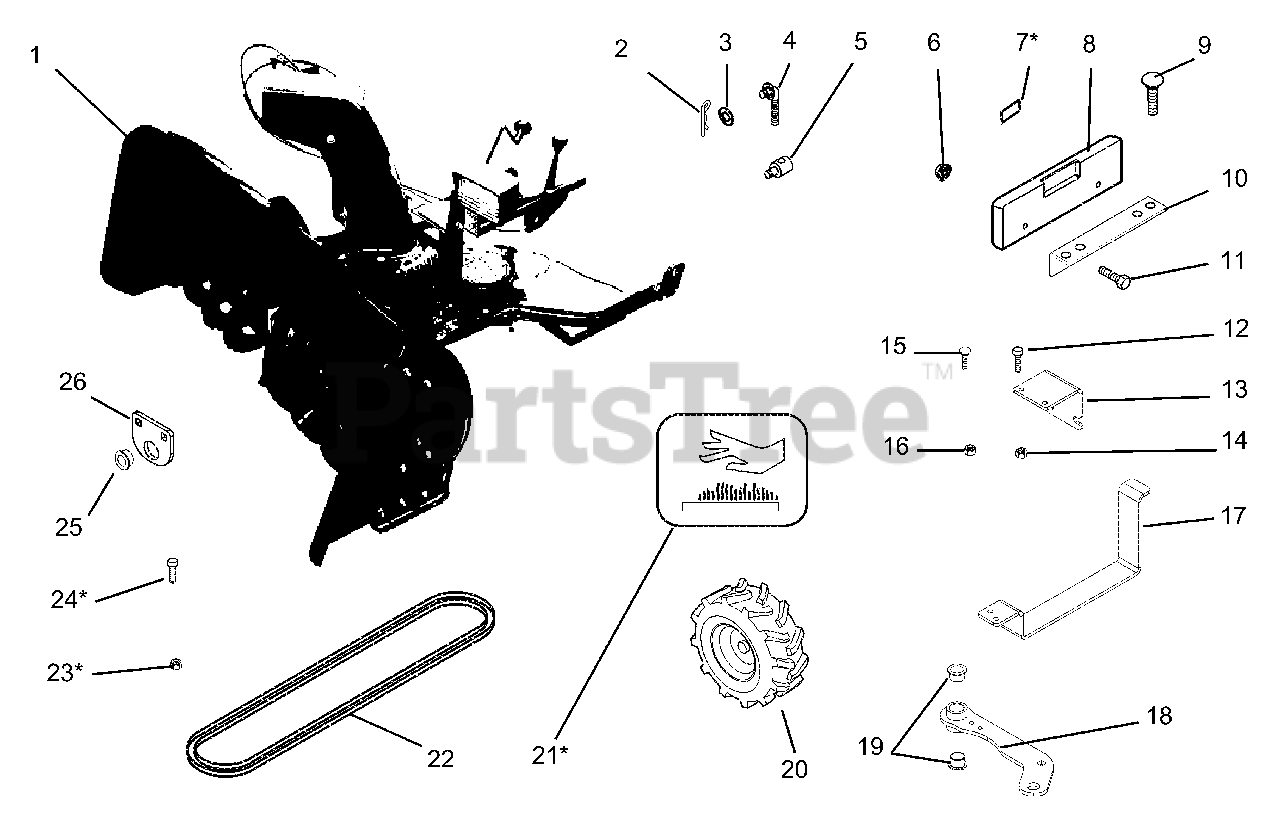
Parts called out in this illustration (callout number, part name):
1	Snow Thrower
2	Hair Pin
3	1-1/4" Flat Washer
4	Lift Link
5	Trunnion
6	3/8" Top Lock Flange Nut
7	Reflector
8	Counterweight
9	3/8" x 2-1/2" Round Head Square Neck Bolt
10	Angle Bracket
11	3/8" x 4-1/2" Hex
12	Bolt 1/4" x 3/4" Hex
13	Bolt Cold Start Latch
14	1/4" Top Lock Flange Nut
15	3/8" x 2" Round Head Square Neck Bolt
16	3/8" Center Jam Nut
17	Cold Start Handle
18	Idler Arm
19	Flanged Bushing
20	Snow Tire
21	Hot Surface Decal
22	PTO Belt
23	5/16" Locknut
24	5/16" 1-12" Shear Bolt
25	Bronze Bushing
26	Rear Pivot Bracket
